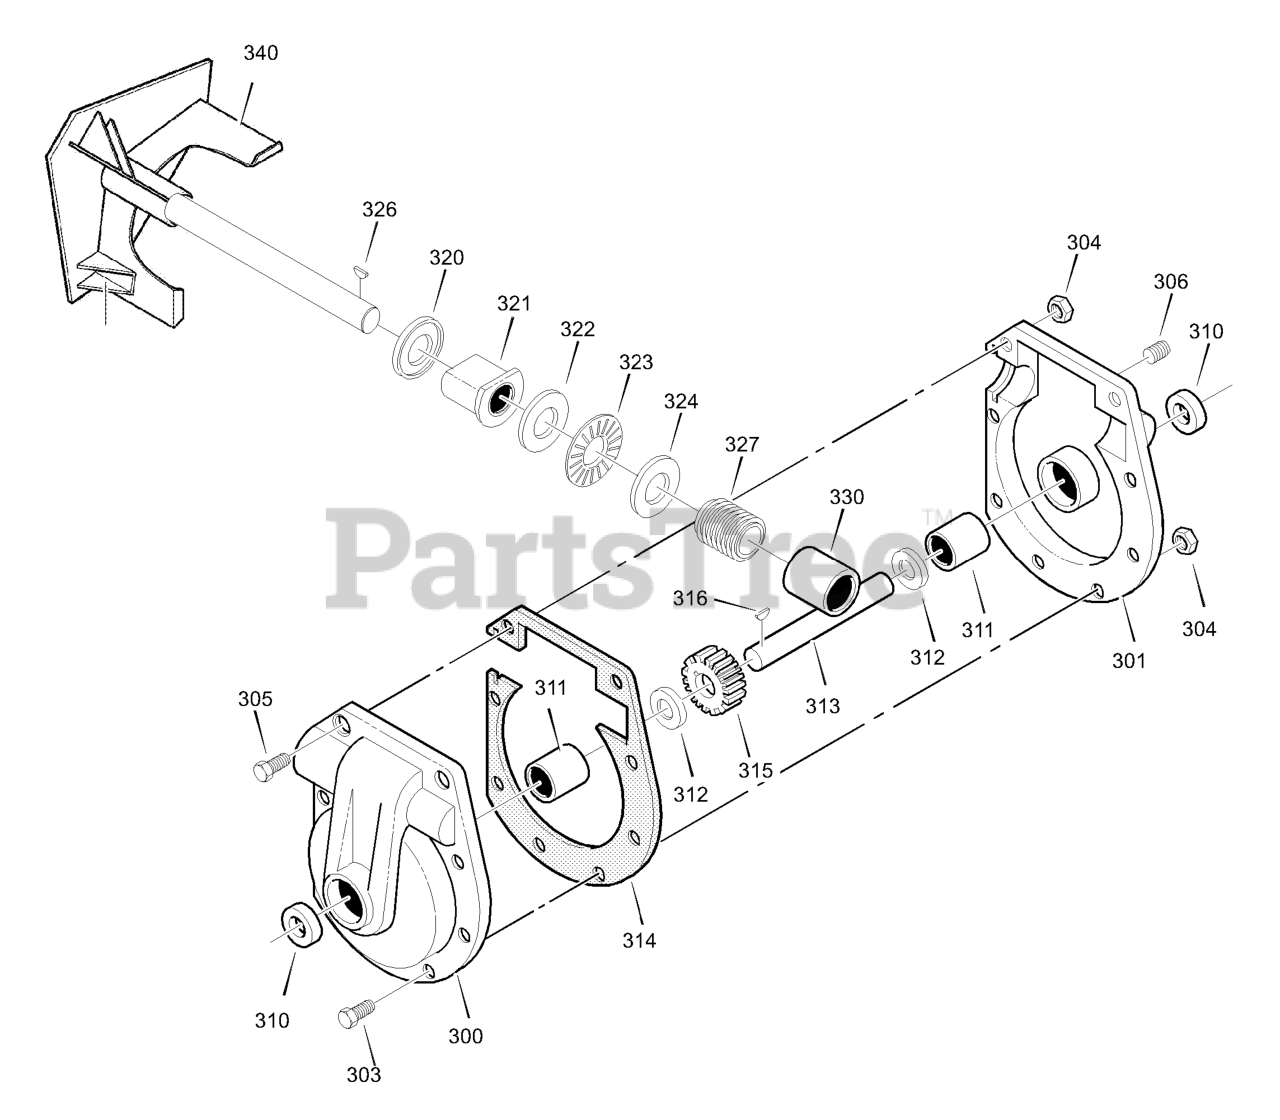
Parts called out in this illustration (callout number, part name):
300	CASE, GEAR, RH
301	CASE, GEAR, LH
303	SCREW,1/4-20X.75
304	NUT,1/4-20
305	NUT, 1/4-20 HEXKEPS
306	PLUG, PIPE
310	SEAL, OIL
311	BEARING, FL
312	WASHER, FLAT
313	SHAFT, AUGER OUTPUT
314	GASKET, GEAR BOX
315	WORM GEAR
316	KEY, WOODRUFF #91
320	BRNG, FL
321	BEARING, FLG
323	BEARING, ROLL
324	WASHER, FLAT
327	GEAR, WORM
330	BEARING, SLV
340	IMPELLER
